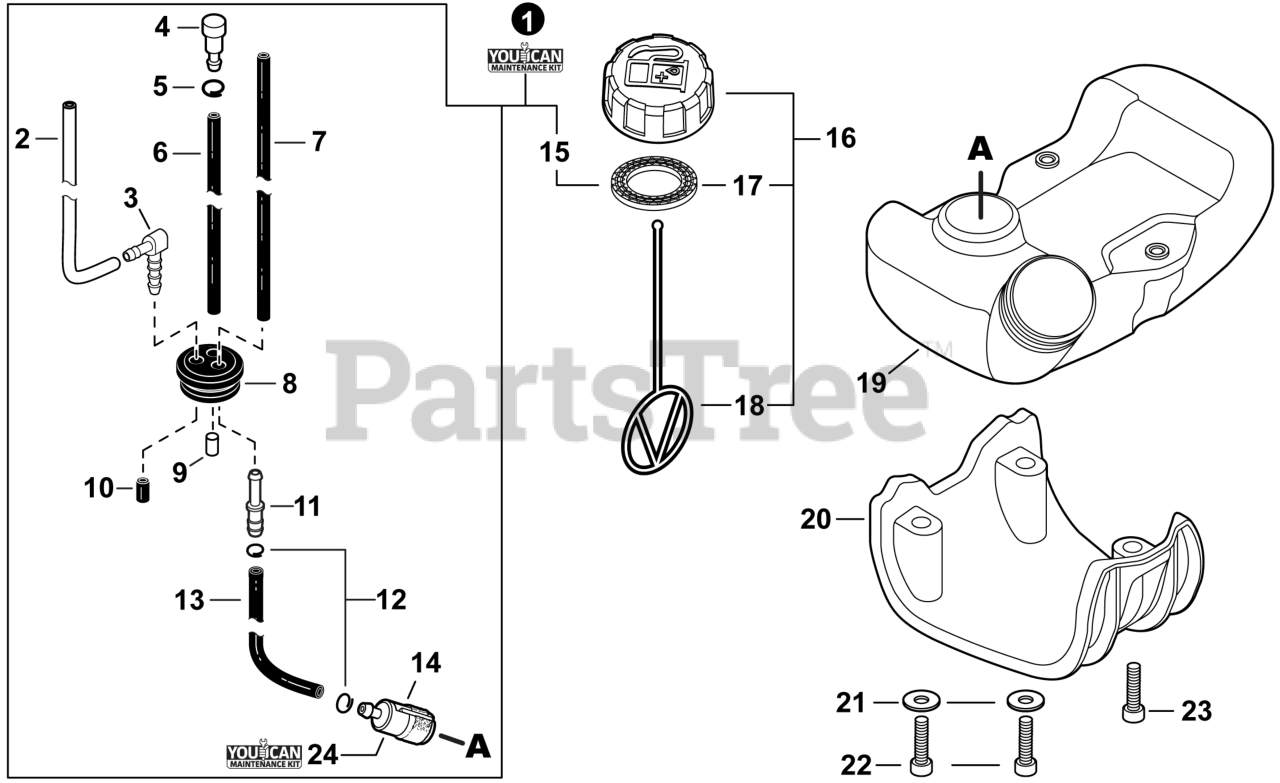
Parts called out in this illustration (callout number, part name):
1	FUEL SYSTEM KIT - YOUCANT
2	PIPE, FUEL 3×6×80 YELLOW
3	CONNECTOR, PIPE
4	VENT ASSY
5	CLIP Ø6.5 MM
6	PIPE, FUEL 3×6×85 BLACK
7	PIPE, FUEL 3×5.5×83 BLACK
8	GROMMET, FUEL
9	FILTER, VENT
10	PIPE, FUEL 3×7×10 BLACK
11	CONNECTOR, PIPE Ø5ר3.5
12	CLIP Ø6
13	PIPE, FUEL - 3×5×125 - BLACK
14	FILTER, FUEL
15	GASKET, FUEL CAP
16	CAP ASSY, FUEL
17	GASKET, FUEL CAP
18	CONNECTOR, CAP L= 123
19	FUEL TANK, (2620 SERIES) 2020
20	GUARD, FUEL TANK
21	WASHER 5.3×10×1
22	BOLT, TORX 5×25
23	BOLT, TORX 5×20
24	TUNE-UP KIT - YOUCANT
